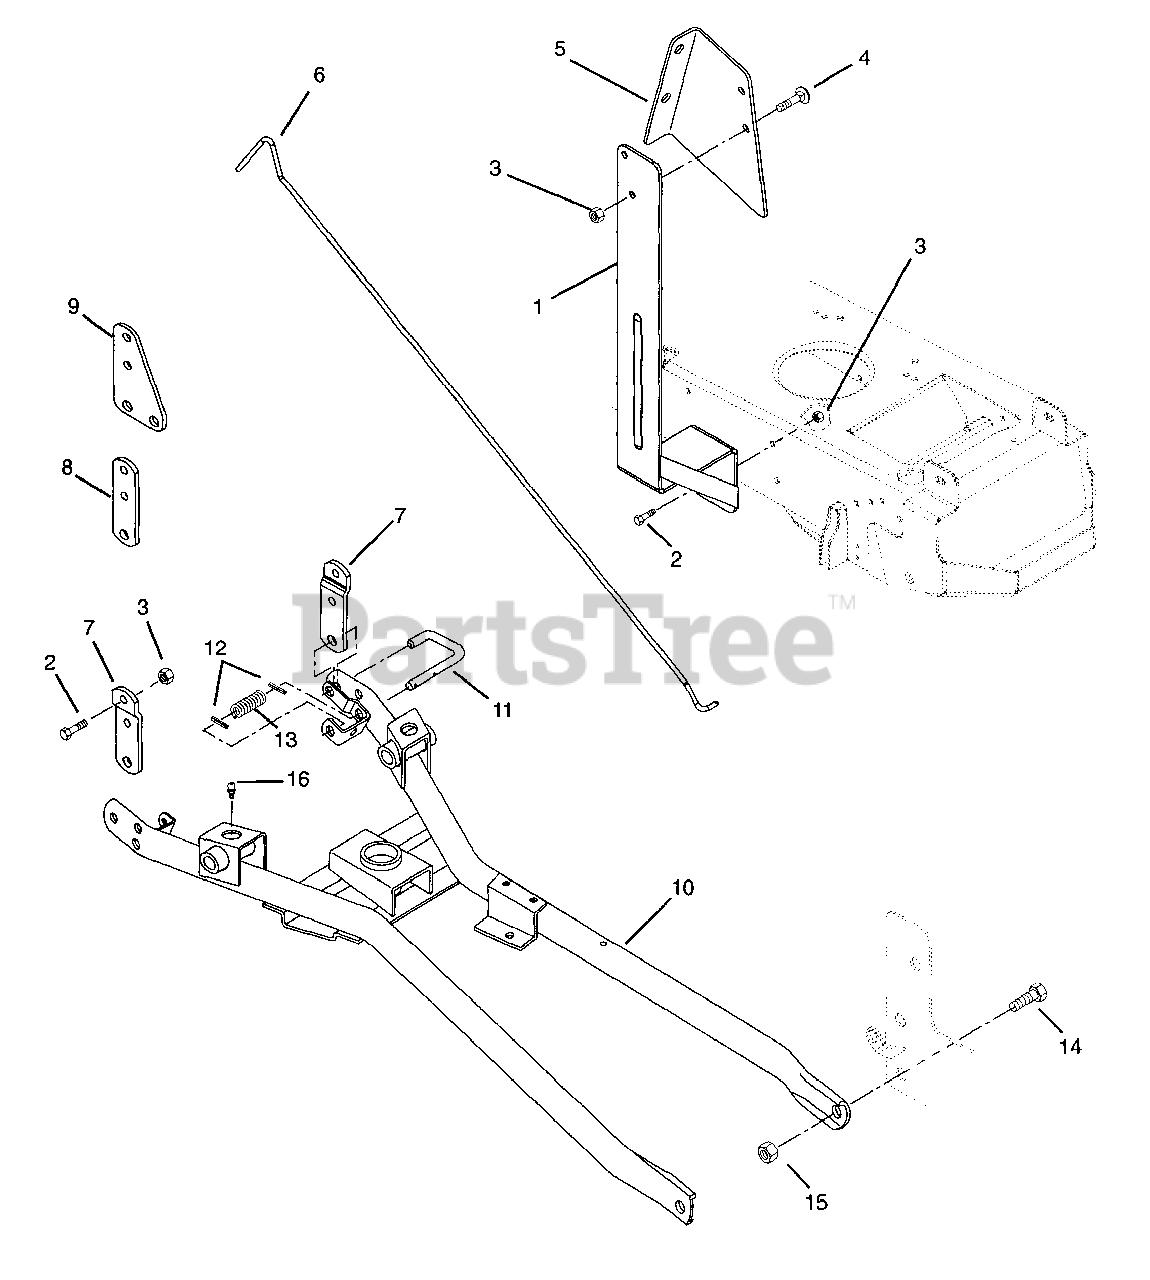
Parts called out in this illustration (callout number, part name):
1	SUPPORT - CONTROL BRACKET
2	@BLT-HEX .38-16X.75 GR5 YWZC
2	@BLT-HEX .38-16X1.00 GR5 YWZC
3	@NUT-LK-CTR .38-16 YWZC
4	BLT-RHHDSQSHNK .38-16X.75 G2YZ
5	CONTROL BRACKET
6	ROD - CONTROL
7	HANGER BRACKET- OFFSET
8	HANGER BRACKET
9	HANGER BRACKET
10	CARRIAGE FRAME WITHOUT SPINDLE
11	LATCH PIN
12	PIN-ROLL .125X.75
13	SPRG, COMP .058X.65X2.13 WLD15
14	@BLT-HEX .62-11X1.50 GR5 YWZC
15	@NUT-LK-CTR .62-11 YWZC
16	FTG-LUBE .25-28X.256 YWZC
